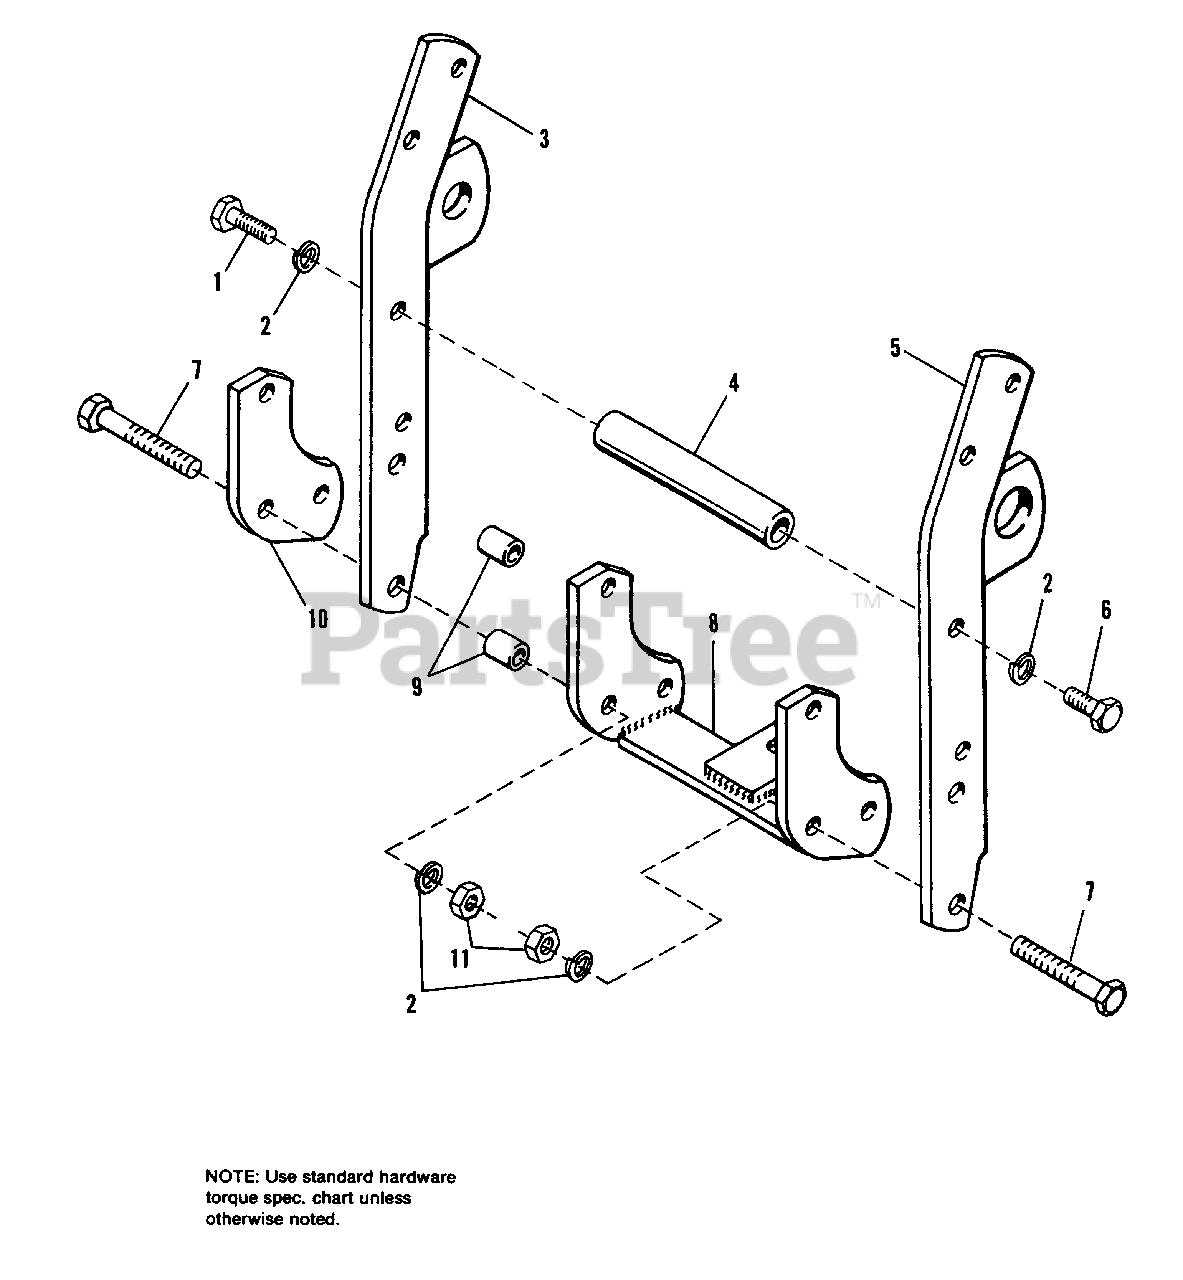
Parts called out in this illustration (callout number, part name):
1	CAPSCREW, Hex Hd., 7/16-14 x 1-3/4
2	LOCKWASHER, 7/16
3	BAR ASSY., Upright
5	BAR ASSY., Upright
6	CAPSCREW, Hex Hd., 7/16-14 x 1-1/4
7	CAPSCREW, Hex Hd., 7/16-14 x 2-3/4
8	BAR ASSY., Draw
11	NUT, Hex, Full, 7/16-14
